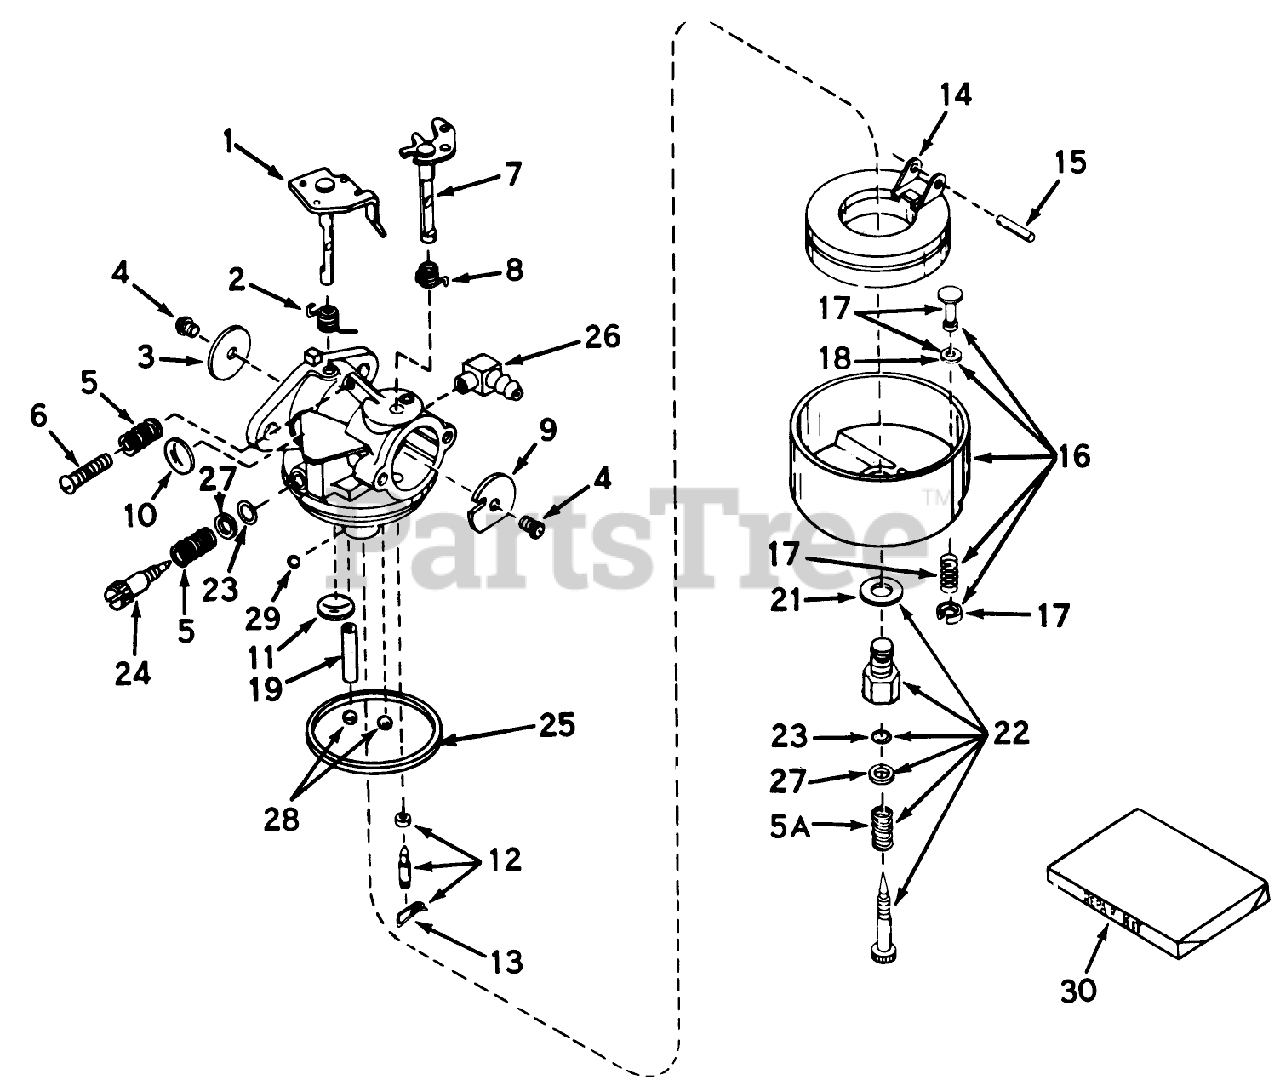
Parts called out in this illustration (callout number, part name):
1	Throttle Shaft and Lever ASM
2	Spring, Throtte Return
3	Shutter-Throttle
4	Screw-Shutter
5	Spring-Tension
5A	Spring
6	Screw-Throttle Crack Screw / Idle Speed
7	Shaft Lever Assy., Choke
8	Spring, Choke return
9	Shutter, Choke
10	Plug-Welch, Idle Mixture Well
11	Plug-Welch, Atmospheric Vent
12	Inlet Needle, Seat Clip Assy. (Incl. No. 13)
13	Clip-Spring
14	Float,Carburetor
15	Shaft-Float
16	Bowl Drain Assy., Float (Incl. No. 17)
17	Bowl Drain ASM
18	Gasket-Plunger, Drain
21	Washer-Bowl Nut
22	Adjustment Screw Assembly, Main (Incl. Nos. 5A, 21, 23 27)
23	ORing
24	Screw, Idle Adj.
25	O Ring-Bowl, Float
26	Fitting Fuel Inlet
27	Washer
28	Plug, Cup
29	BalI, Steel
30	Repair Kit
